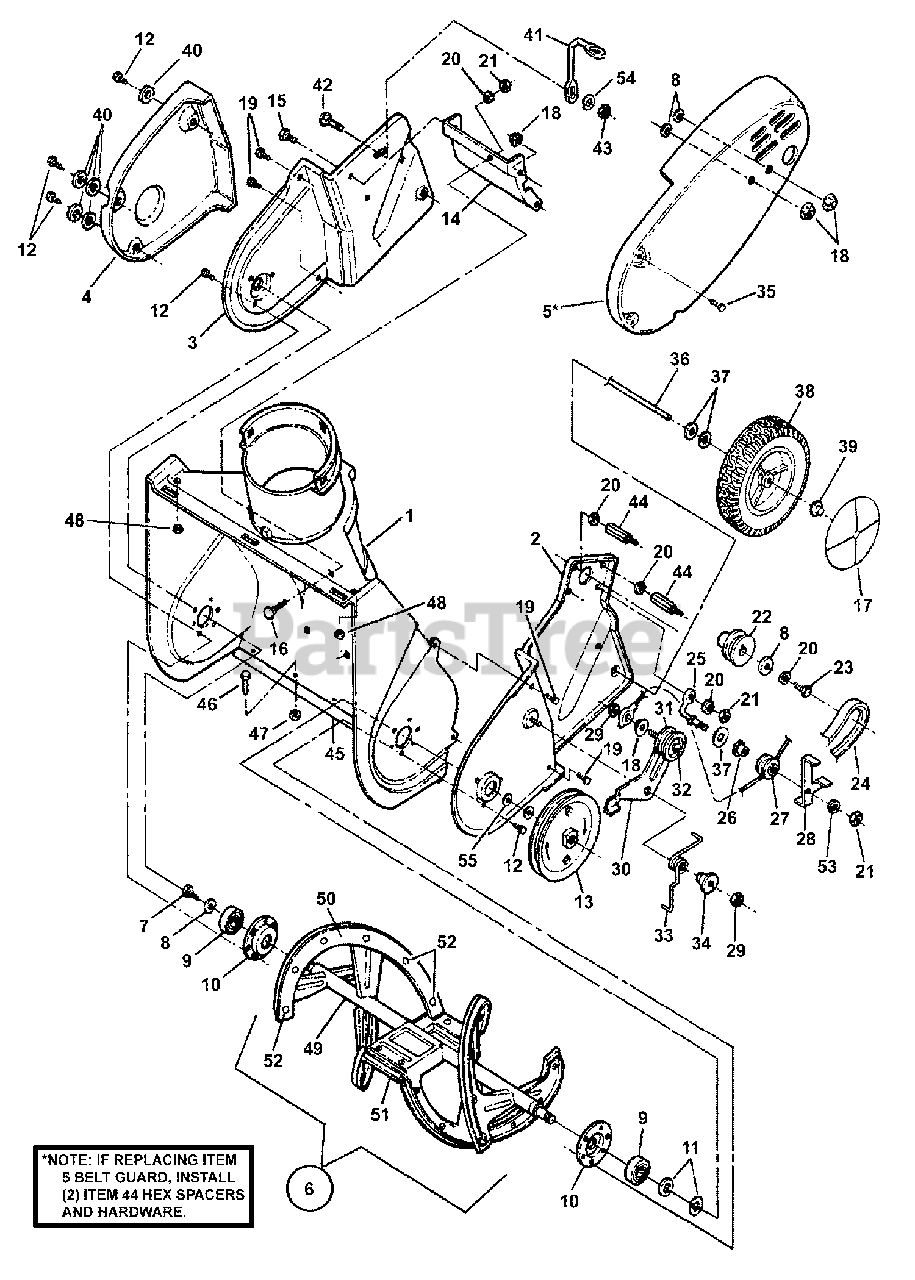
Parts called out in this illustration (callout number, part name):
1	* ASSEMBLY, Auger Housing
1	ASSEMBLY, Auger Housing
2	ASSEMBLY, End Frame, L.H.
3	FRAME, End, R.H.
4	COVER, R.H. Side
5	** GUARD, Belt Drive
6	ASSEMBLY, Auger (incl. items 49 thru 52)
7	SCREW, 5/16-18 x 5/8" Hex Washer Self-Tap
8	WASHER, 5/16" Flat
9	BALL BEARING
10	RETAINER, 1-3/4" O.D. Bearing
11	WASHER, 3/4" Shim
12	SCREW, #10-32 x 3/8" Hex Washer Self-Tap (Torx)
13	PULLEY
14	BRACE, Engine
15	SCREW, 1/4-20 x 3/8" Hex Washer Self-Tap
16	BOLT, 5/16-18 x 3/4" Short Neck Carriage, GR 5
17	COVER, Wheel
18	NUT, 5/16-18 Hex Flange Lock, GR 5
19	SCREW, 1/4-15X3/4, Self-Tapping, BZ
20	WASHER, 5/16" Split Lock
21	NUT, 5/16-18 Hex
22	PULLEY, Engine
23	SCREW, 5/16-24 x 3/4" Hex Head Cap, GR 5
24	V-BELT, 3L Section, 34.27" effective length
25	GUIDE, Cable
26	BUSHING, Flange
27	PULLEY, Nylon
28	GUIDE, Belt
29	NUT, 5/16-18 Hex Center Lock
30	BRACKET, Idler Pivot
31	PULLEY, Idler
31	PULLEY, Single Flange Idler
32	SCREW, 5/16-18 x 1-3/4" Hex Head Cap, GR 5
33	SPRING, Idler Torsion
34	BUSHING, Pivot
35	SCREW, #10-16 x 3/4" Pan Head Self-Tap
36	AXLE, 3/8" Dia. Wheel
37	WASHER, 3/8" Flat
38	WHEEL, 7 x 1.50
38	WHEEL, 7"
39	PUSH NUT, 3/8"
40	WASHER, #10 Flat
41	SUPPORT, Fuel Tank
42	BOLT, 1/4-20 x 5/8" Short Neck Carriage, GR 5
43	NUT, 1/4-20 Hex Nyloc
44	SPACER, Hex (2.69" long)
44	SPACER, Hex (3.69" long)
45	BLADE, Scraper
46	SCREW, 1/4-20 x 1/2" Pan Head Machine (Torx)
47	NUT, 1/4-20 Hex Nyloc
48	NUT, 1/4-20 Hex Center Lock
49	WELDMENT, Auger
50	SHOE, Flite
51	SHOE, Flite
51	SHOE, Center Flite
52	SCREW, #10-24 x 1/2" Hex Washer Self-Tap Sems
53	WASHER, 5/16" Internal Tooth Lock
54	WASHER, 1/4" Split Lock
55	WASHER, 3/4" Flat
